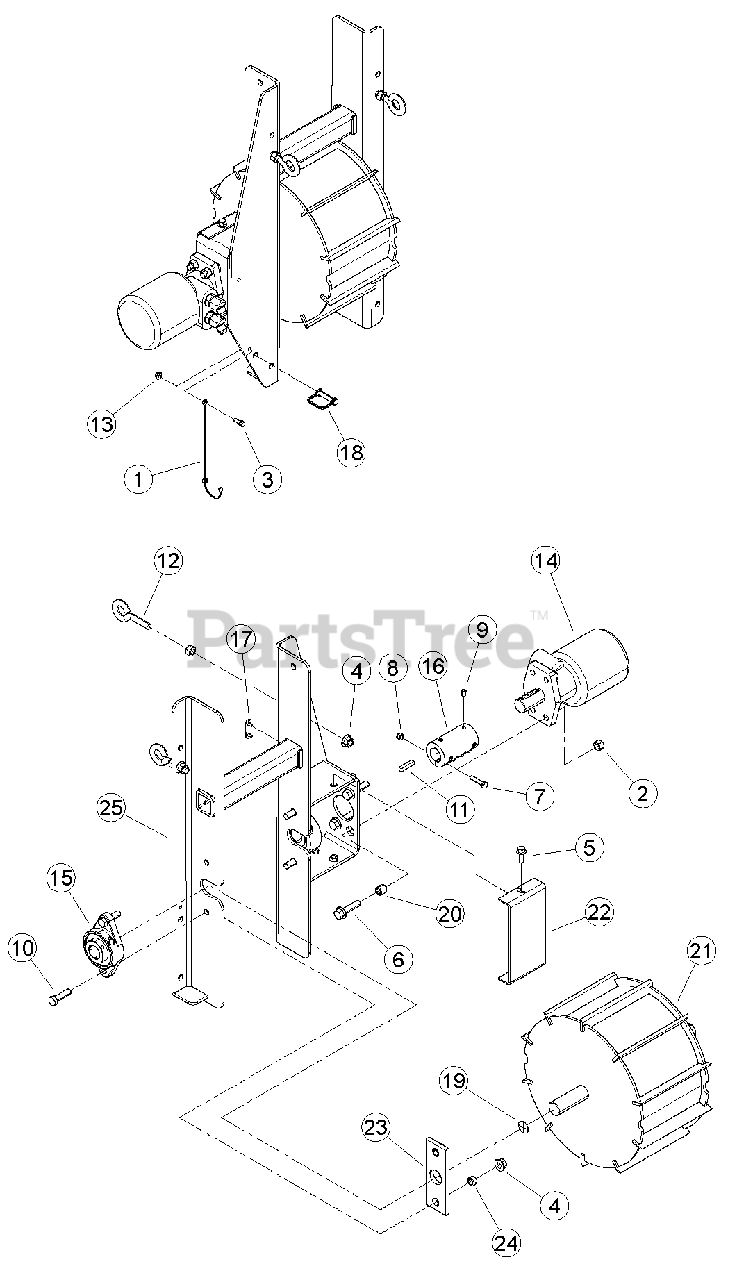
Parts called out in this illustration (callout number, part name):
1	LANYARD, NYLON
2	NUT, 1/2" CENTERLOCK GRB ZP
3	BOLT, 1/4-20 X 3/4 HWH GR5 CZP
4	NUT, 1/2-13 NYLOCK FLANGE
5	BOLT, 3/8 X 1 FLANGE NC
6	BOLT, 1/2-13 X 2 HWH GR5 CZP
7	BOLT, 5/16 X 1-1/2 GR5 HEX CPS ZP
8	NUT, 5/16" NE NYLOCK ZP
9	SET SCREW, 3/8 X 1/2 CUP PT SKT
10	BOLT, 1/2 X 1-3/4 GR5 HCPS NC ZP
11	KEY, 5/16 X 1-1/2 SQUARE
12	EYEBOLT, 1/2 X 2" ZP
13	NUT, 1/4-20 NYLOCK-FLANGE
14	MOTOR, 45 CU IN HYDRAULIC
15	BEARING, 1-1/4" DIA 2 BOLT FLANGE
16	COUPLER, 1-1/4 SHAFT
17	WEAR PAD, STD. SPRING HD FRONT
18	PIN, SNAP 3/8 X 1-1/2 USABLE LGH
19	DECAL, ROTATING SHAFT
20	SPACER, 0.75 X 0.620
21	WELDMENT, TOP GRAB ROLLER
22	SHIELD, COUPLER
23	BEARING, SLIDE
24	SPACER, .75 OD X .5 ID X .37
25	WELDMENT, ROLLER SLIDE
